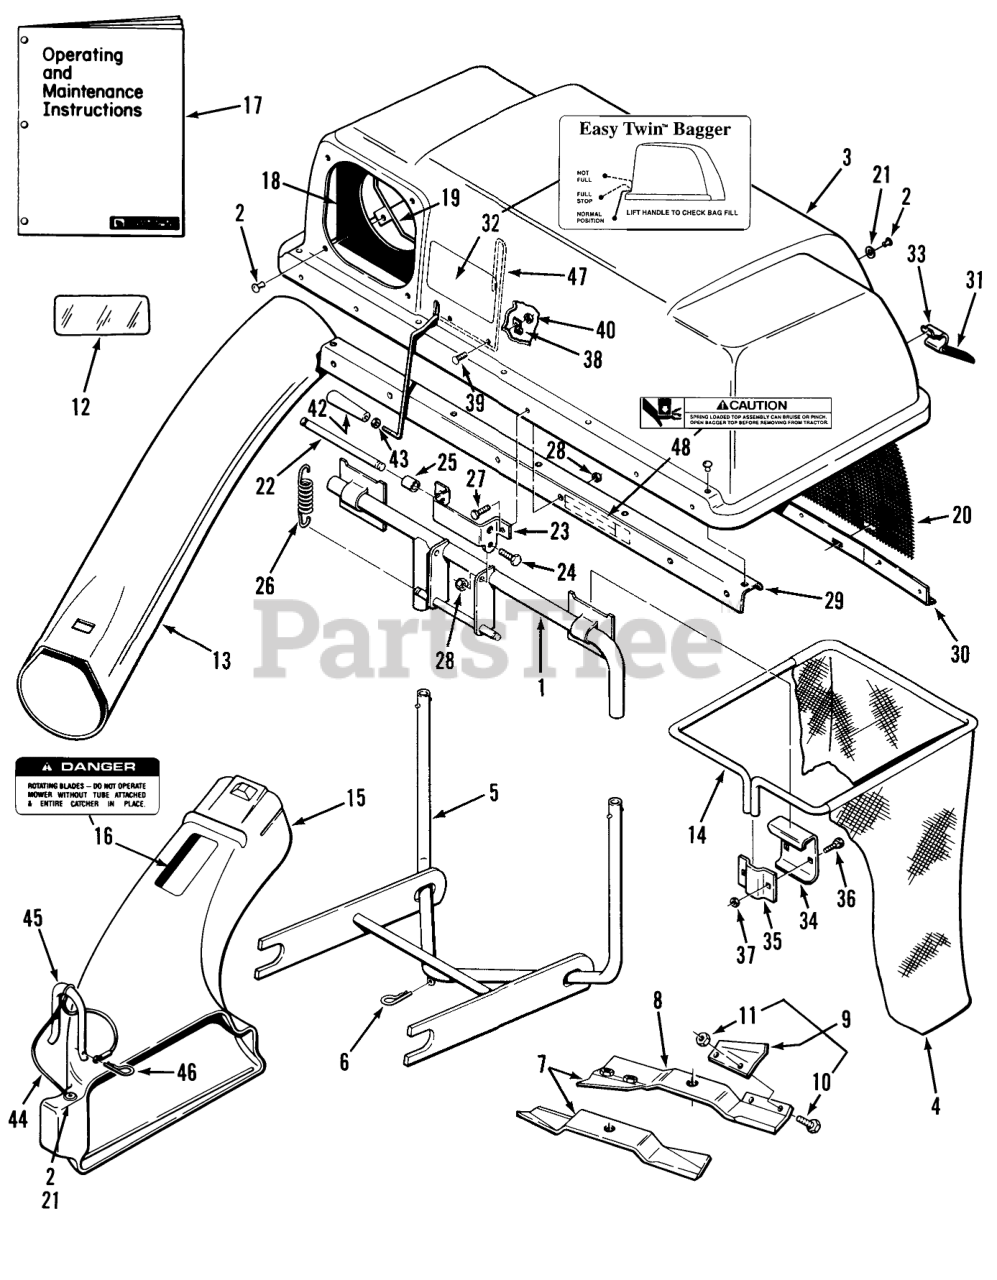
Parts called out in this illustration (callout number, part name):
1	FRAME ASM
2	RIVET-BLIND
3	TOP-BAGGER
4	BAG-18" DEPTH
5	ASS'Y-QUICK ATTAC B
6	Hairpin
7	Blade Kit (includes LH blade, RH blade with tabs)
8	High Lift Blade (includes item 9) RH side
9	Lift Tab Kit (includes items 10 & 11)
10	BOLT 5/16-18X5/8
11	NUT-LOCK 5/16-18
12	DECAL-OVERLAY
13	CHUTE-BAGGER (L)
14	Bag Frame
15	Discharge Elbow (includes items 16 & 44 installed)
16	DECAL-DANGER
17	Operating and Maintenance Instructions
18	Chute Seal
19	CLAMP-SEAL
20	SCREEN-BAGGER
21	Washer
22	PIN-SPRING
23	HINGE-BAG TOPB
24	Bolt
25	SPACER
26	SPRING-EXTENSION
27	BOLT
28	NUT
29	Bagger-Stiffener
30	SUPPORT-SCREEN B
32	Decal-Full Bag Test
33	Latch-Bag
34	Bag Hanger
35	Clamp
36	Bolt
37	Nut
38	CLIP
39	Screw
40	Nut
42	HANDLE-TAPERED
43	Nut
44	LANYARD-ELBOW LATCH
45	LATCH-ELBOW
46	Hairpin Cotter
47	FEELER-FILL, BAG
48	DECAL-CAUTION
